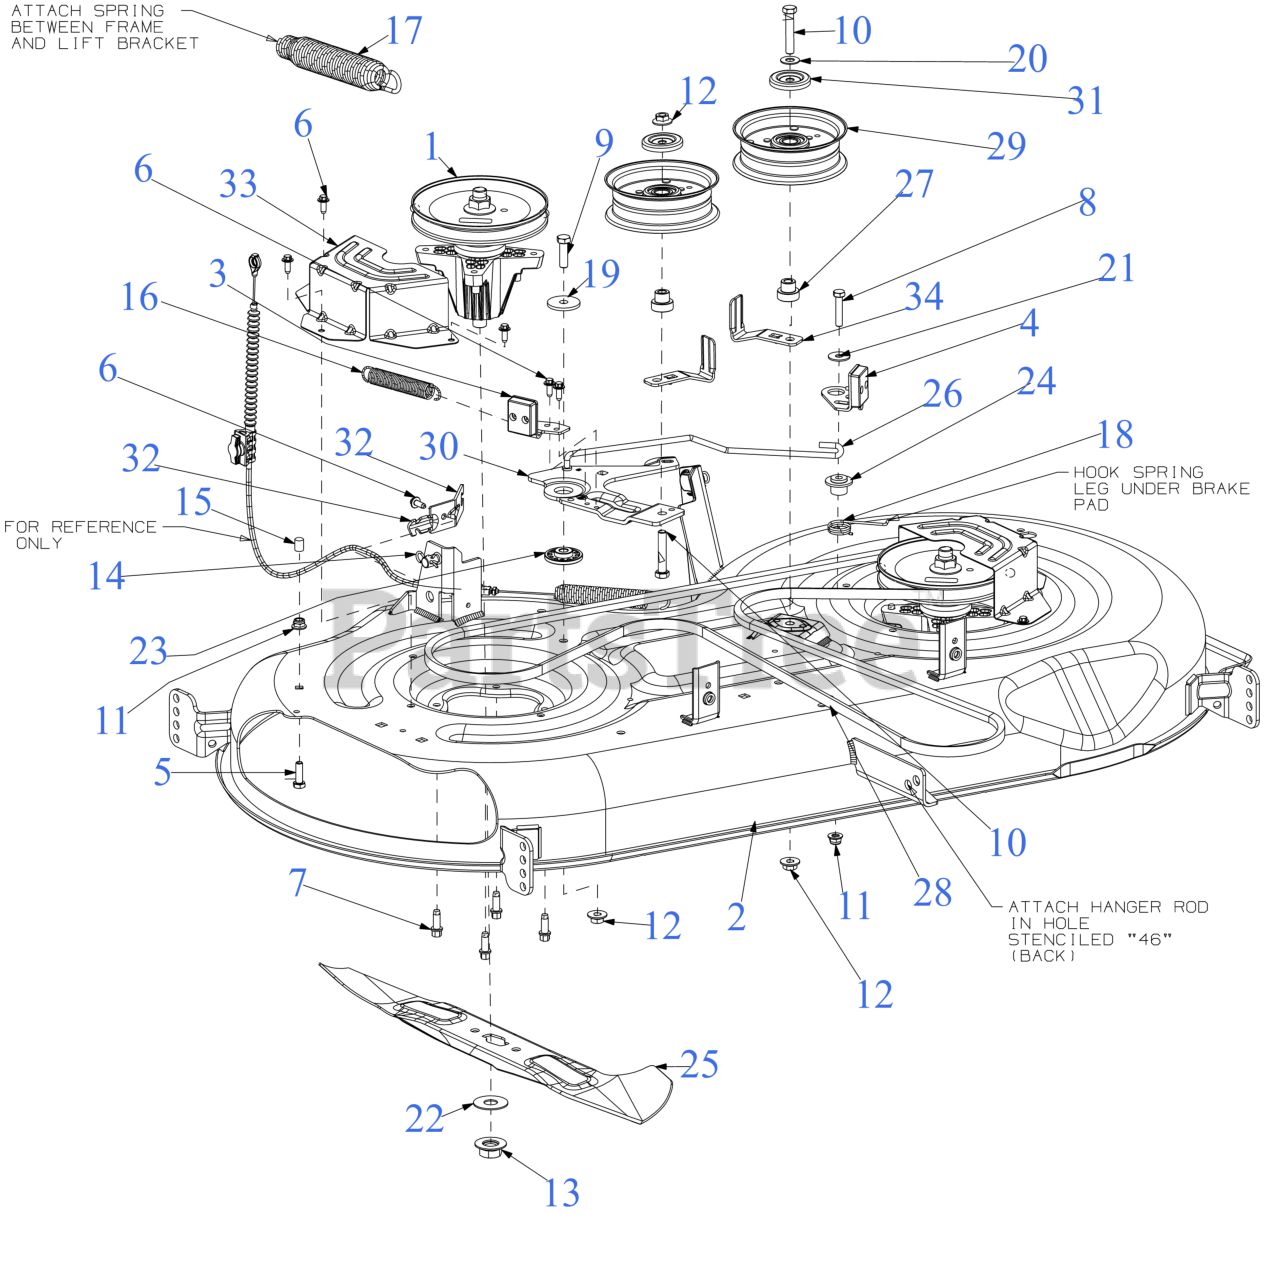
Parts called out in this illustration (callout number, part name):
1	SPINDLE ASSEMBLY (6.93 DIA)
3	DECK BRAKE ASSEMBLY (RH)
4	DECK BRAKE ASSEMBLY
5	SCREW 5/16-18 x 1.0 GR5
6	SCREW M6-1 x .625
7	SCREW 5/16-18 x .875
8	SCREW 5/16-18 x 1.5 LG
9	SCREW 3/8-16 x 1.25 GR5
10	SCREW 3/8-16 x 2.0 GR 8
11	FLANGE LOCK NUT 5/16-18
12	FLANGE LOCK NUT
13	HEX FLANGE NUT 5/8-18 GR5
14	BOW TIE COTTER PIN
16	EXTENSION SPRING
17	LIFT ASSIST SPRING (SMALL)
18	TORSION SPRING
19	FLAT WASHER .390x1.500x.134
20	FLAT WASHER .401X.88
21	FLAT WASHER 344X1.00
22	FLAT WASHER .635X1.585X.062 HDN
23	SHOULDER SPACER
24	DOUBLE SHOULDER SPACER .750 x .135
25	23.25" BLADE (2IN1) (S SHAPE CENTER HOLE)
25	Cub Cadet 46" HI LIFT BLADE SET (S SHAPE CENTER HOLE) (-05510)
25	Troy-Bilt 46" HI LIFT BLADE SET (S SHAPE CENTER HOLE) (-05510)
25	23.25" XTREME BLADE (2IN1) (S SHAPE CENTER HOLE)
25	Cub Cadet 46" XTREME BLADE SET (S SHAPE CENTER HOLE) ( -05510-X)
25	Troy-Bilt 46" XTREME BLADE SET (S SHAPE CENTER HOLE) (-05510-X)
25	23.25" LOW LIFT BLADE (S SHAPE CENTER HOLE)
25	Cub Cadet 46" LOW LIFT BLADE SET (S SHAPE CENTER HOLE) (-05510-L)
25	Troy-Bilt 46" LOW LIFT BLADE SET (S SHAPE CENTER HOLE) (-05510-L)
26	DECK BRAKE ROD
27	SHOULDER SPACER
28	V-BELT A SEC x 108.3
28	Cub Cadet 46" DECK DRIVE BELT
28	Genuine Factory Parts 46"DECK DRIVE BELT
29	IDLER PULLEY 4.50" DIA
30	46" IDLER PIVOT BRACKET
31	IDLER PULLEY CAP
32	ENGAGEMENT CABLE BRACKET
